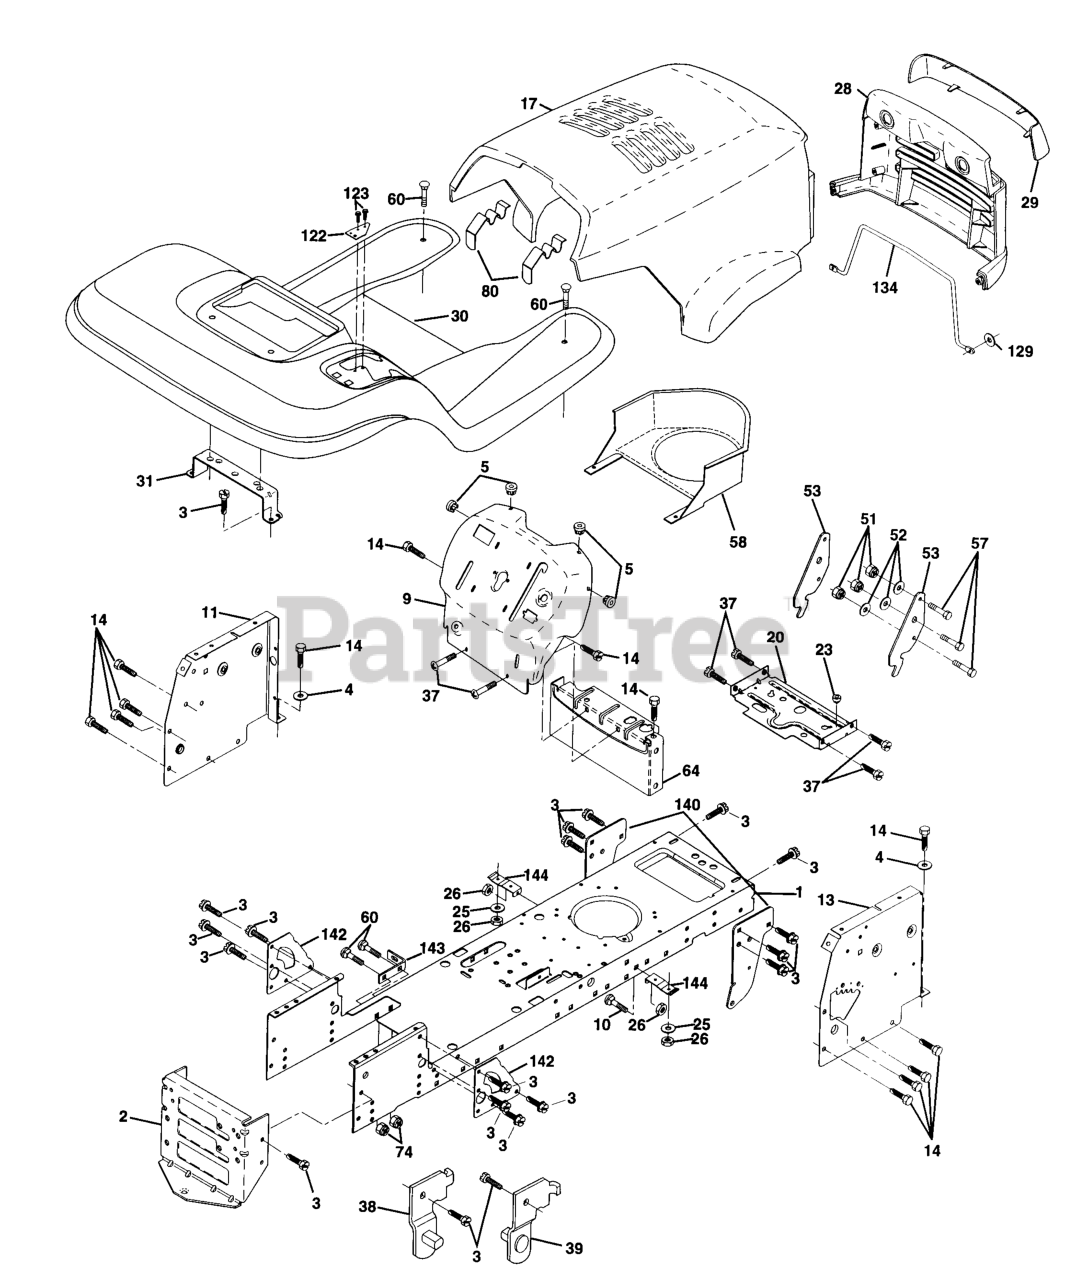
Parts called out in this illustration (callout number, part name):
1	CHASSIS WELDMENT
2	STRETCH DRAWBAR
3	SCREW
4	Washer 13/32 x 3/4 x 16 Ga.
5	BUMPER.RUBBER.HOOD
9	DASH P/L GREY LTH-120
10	BOLT D
11	PANEL DASH LH
13	PANEL DASH RH
14	SCREW LT
17	HOOD - LT/YT
20	PLATE MTG
23	BUSHING.SNAP.NYL.BLK.
25	WASHER
26	NUT
28	GRILLE LT/PL HUSQVARNA
29	LENS LT/PL HUSQVARNA
30	FENDER FOOTREST
31	BRACKET.SUPPORT.FENDER
37	Screw Thdrol 6/16-18 x 1/2 TYT
38	BRACKET LH PIVOT
39	BRACKET RH PIVOT
51	LOCKNUT.NYLOC.1/4-20
52	WASHER
53	BRACKET PNT PICK OFF LT/PL
57	BOLT
58	AIR DUCT P/L/LT
60	Bolt Rdhd Sqnk 3/8-16 unc x 3/4
64	DASH LOWER
80	LATCH HOOD
129	WASHER
134	ROD SUPPORT HOOD LT/PL HUSQ
140	BRACKET CHASSIS FRONT
142	PLATE REINFORCEMENT
143	BRACKET, SWAY BAR
144	BRACKET FOOTREST
146	SCREW TORX HD 5/16X18
